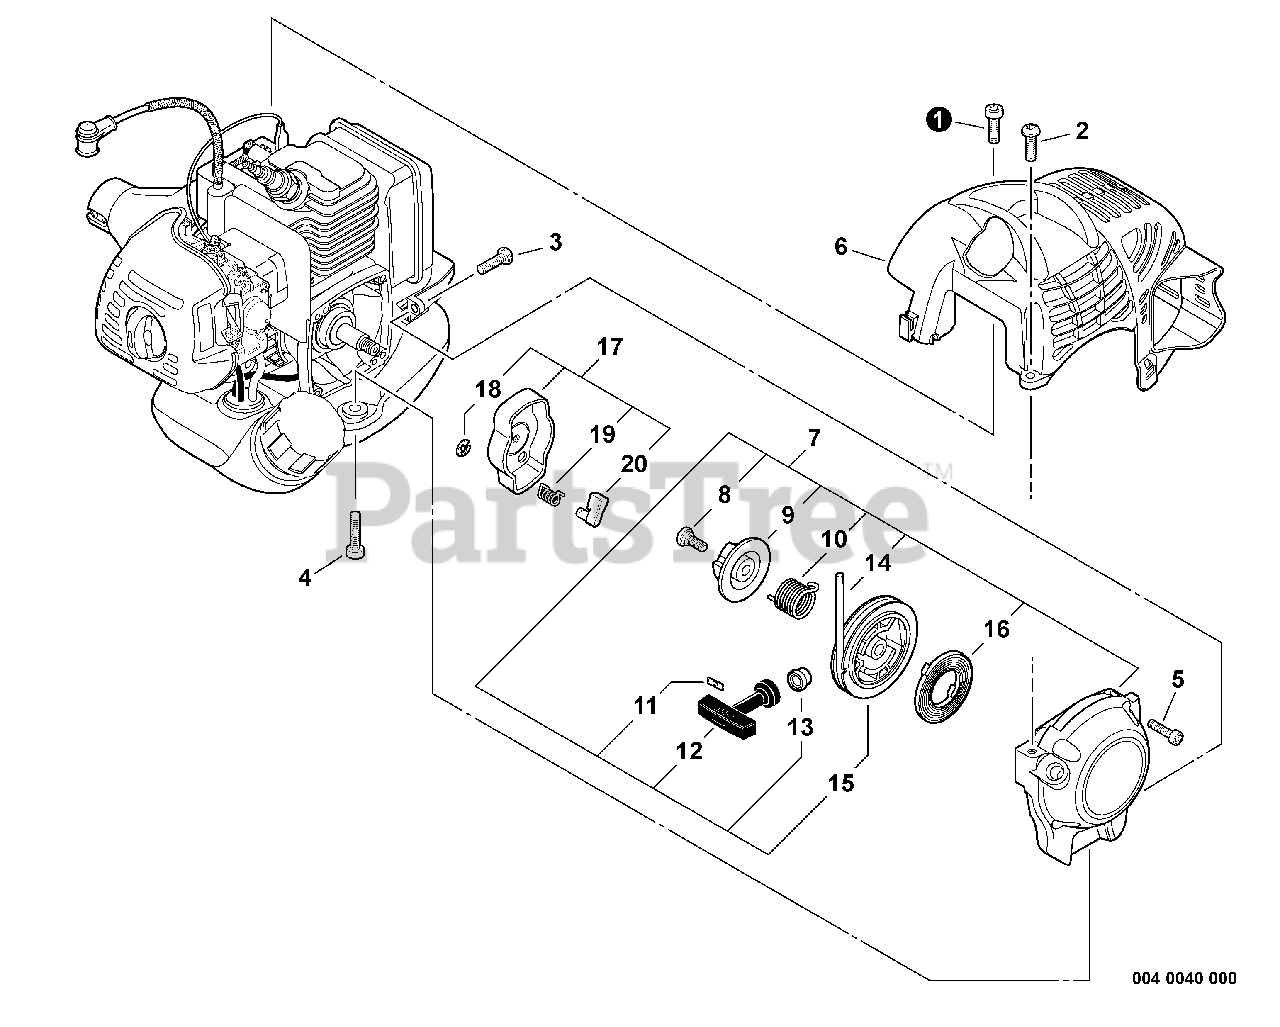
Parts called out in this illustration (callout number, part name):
1	BOLT, TORX 5×16
2	BOLT, TORX 5×16
3	BOLT, TORX 5×16
4	BOLT, TORX 5×20
5	BOLT, TORX 4×16
6	COVER, ENGINE
7	STARTER, RECOIL
8	SCREW
9	PLATE, CAM (NLA SEE PB 15-06)
10	SPRING, TORSION
11	RETAINER, ROPE
12	GRIP, STARTER
13	GUIDE, ROPE
14	ROPE, STARTER 3×700
15	REEL, ROPE
16	SPRING, RECOIL
17	PAWL ASSY, STARTER
18	E-RING 4
19	SPRING, RETURN
20	PAWL, STARTER
